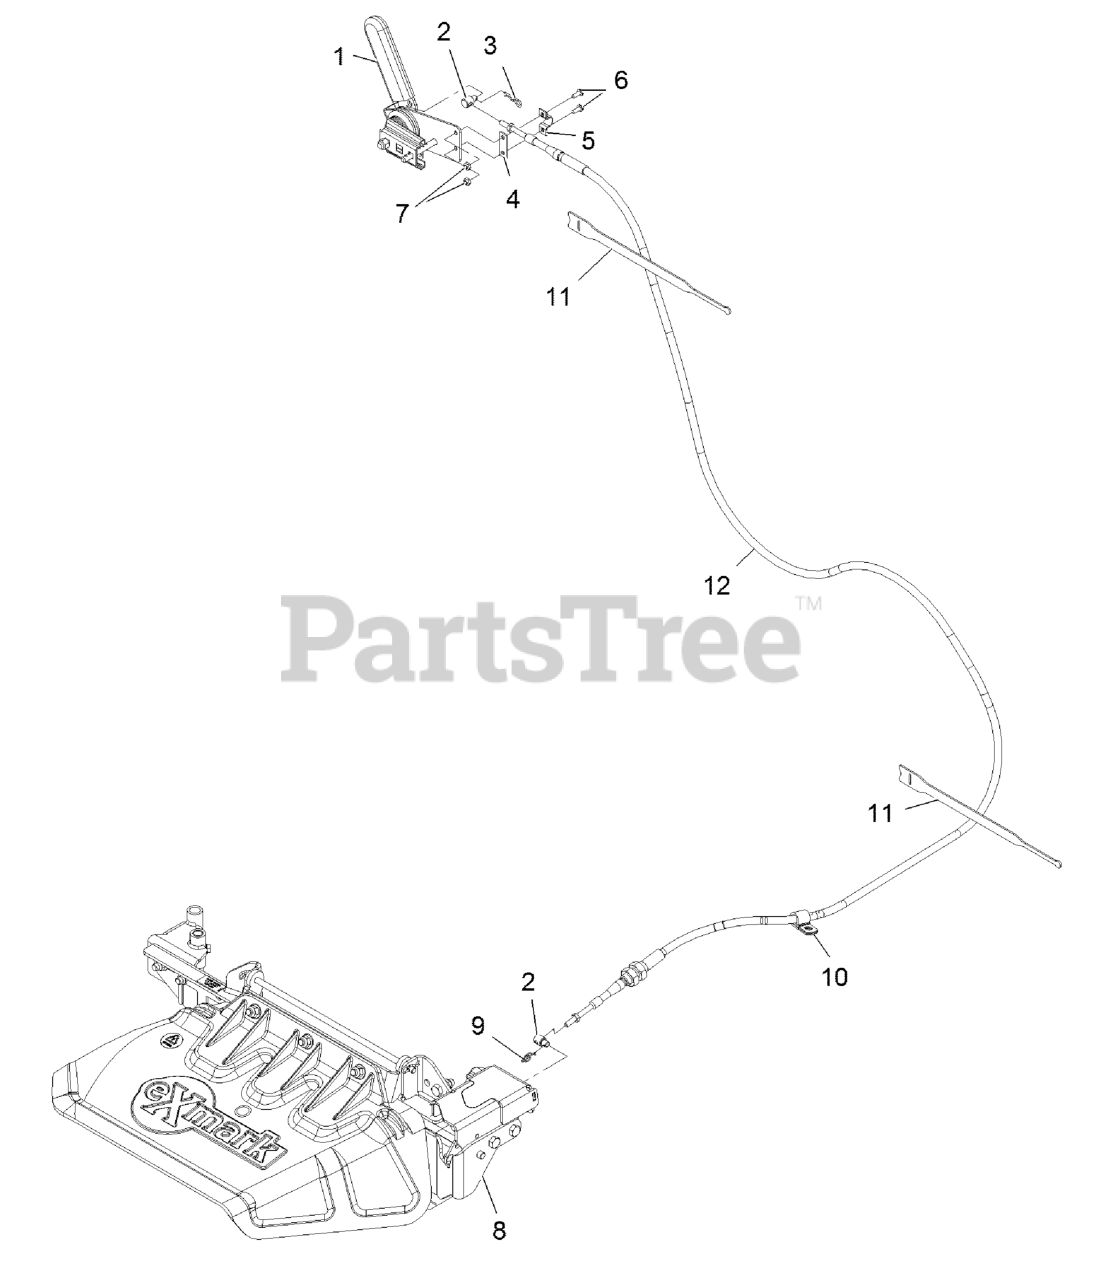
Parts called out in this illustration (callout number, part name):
1	ASM, HAND LEVER
2	PIVOT, CONTROL CABLE
3	PIN-COTTER
4	SHIM,CONTROL CABLE
6	SCREW-PPH
7	NUT-LOCK, NI
8	ASM, OCD
9	PIN-COTTER, LOCKING
10	CLIP-LOOM
11	STRAP-VELCRO, CABLE TIE
12	CABLE-DISCHARGE GATE
